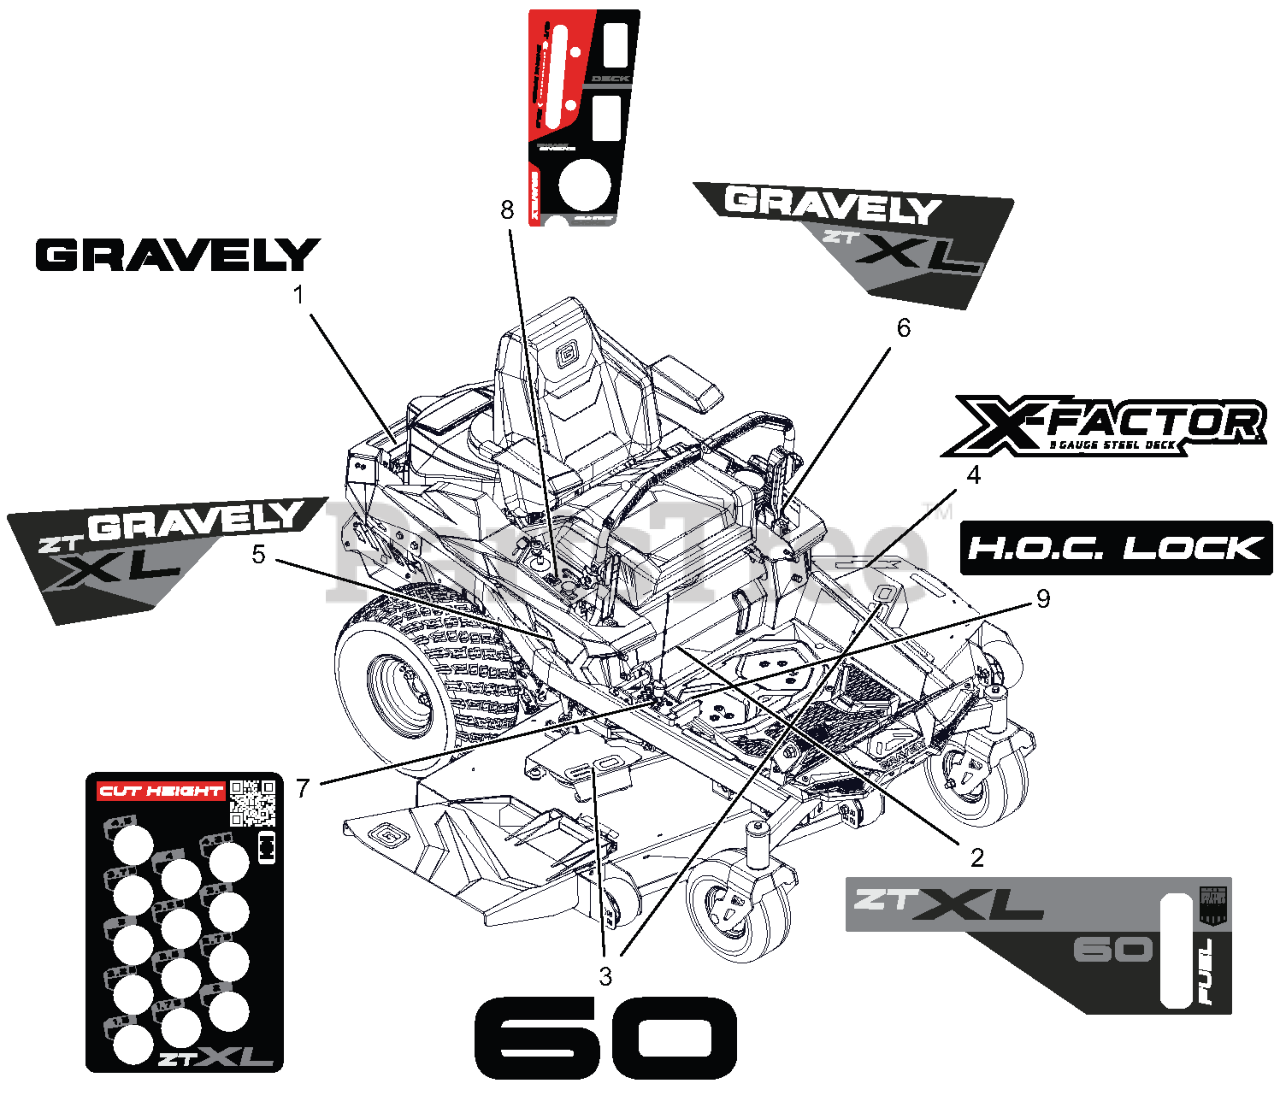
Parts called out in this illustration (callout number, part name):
1	DECAL- GRAVELY
2	DECAL- ZTXL 60-KICK PLATE
3	DECAL- DECK 60"
4	DECAL- DECK X-FACTOR
5	DECAL- ZT XL FENDER RH
6	DECAL- ZT XL FENDER LH
7	DECAL- HEIGHT OF CUT-XL
8	DECAL- CONTROL PANEL-GRAVELY
9	DECAL- HOC LOCK
